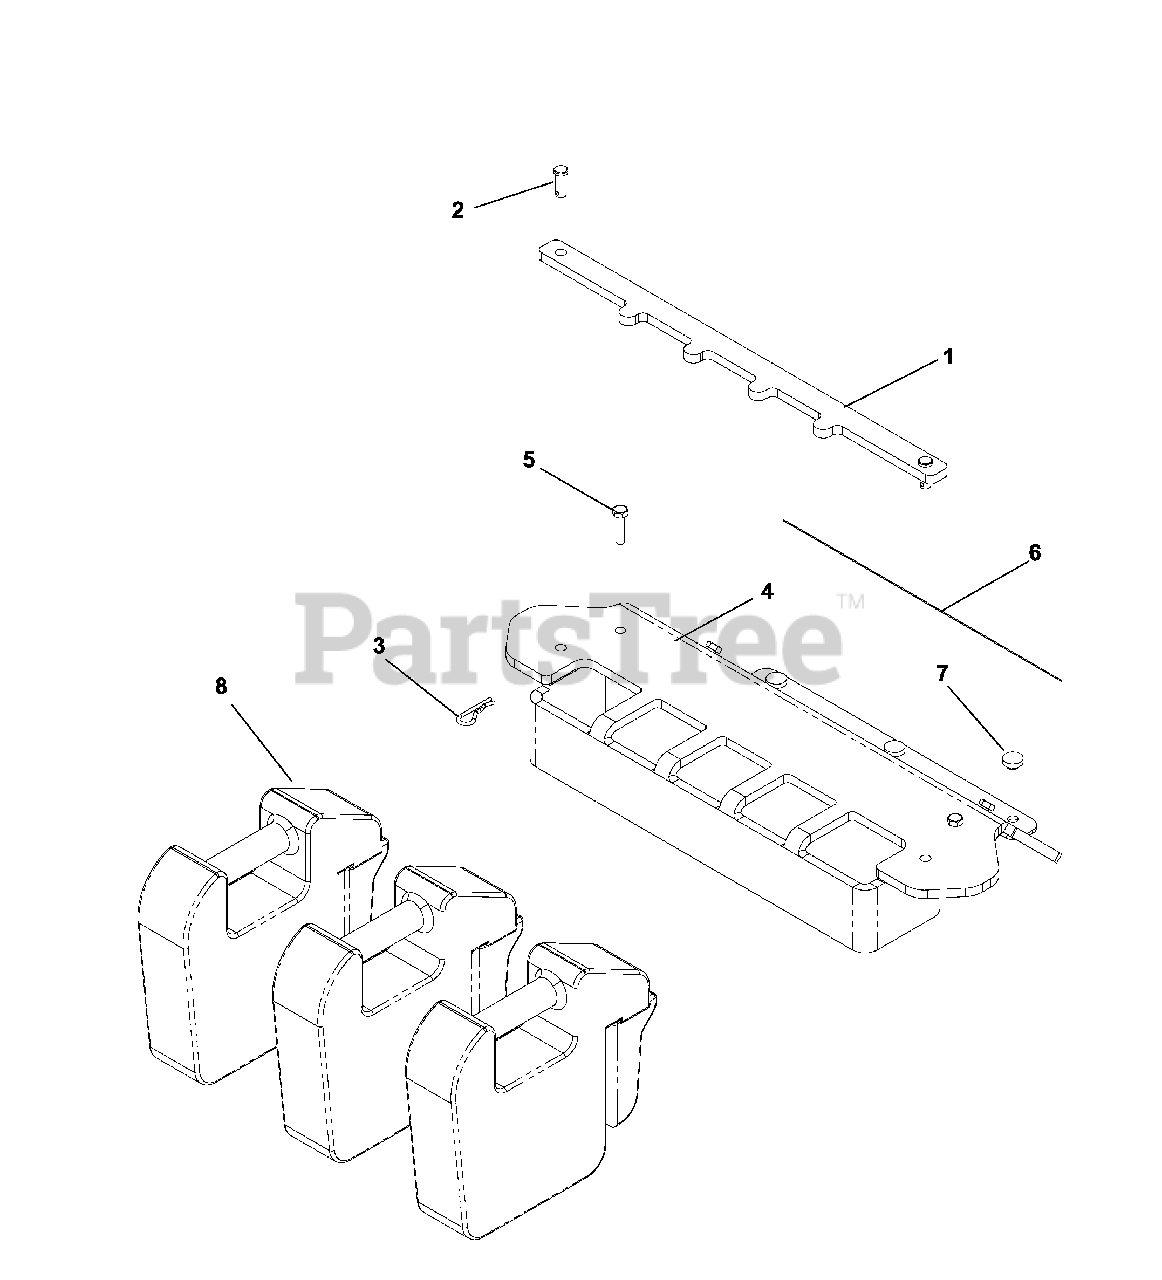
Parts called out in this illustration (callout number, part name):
1	HOLD DOWN, WEIGHT BAR
2	CLEVIS PIN
3	RETAINER SPRING
4	WEIGHT BAR
5	HCS 5/16C X 1 1/4
6	ANTI-SKID PAD
7	GROMMET, BUMPER
8	FRT WEIGHT CAST PZ DFS
